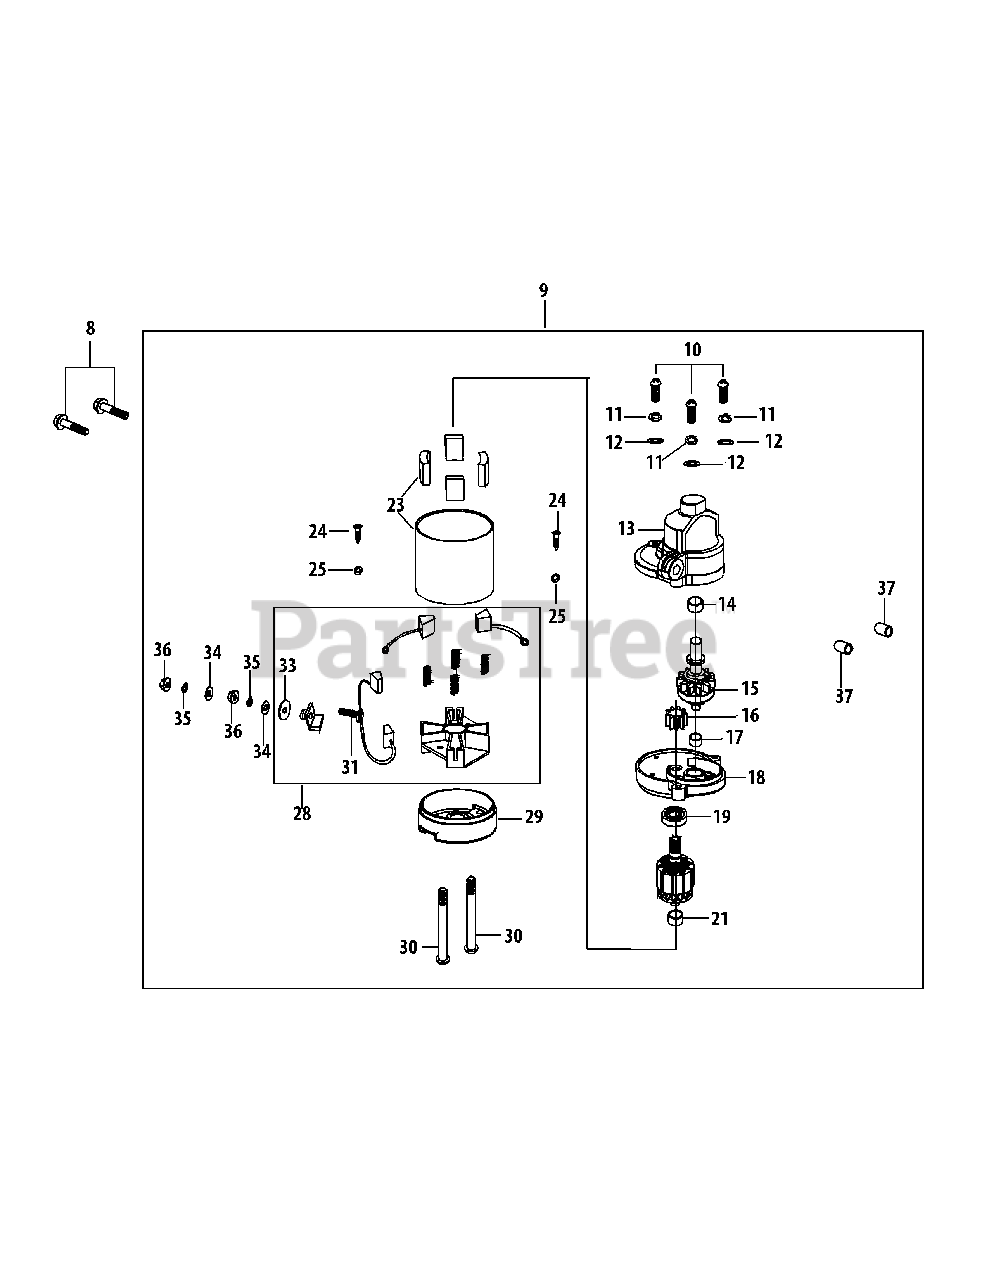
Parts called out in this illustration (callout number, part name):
8	Bolt M8×40
9	Starter Assembly
10	Screw M5×25
11	Lock Washer
12	Plain Washer
13	Electrical Starter Front Cover
15	Pinion/Clutch Assembly
18	Pinion Cover
19	Bearing 6001Zz
23	Starter Housing Assembly
25	Lock Washer
28	Brush Assembly
29	Electrical Starter Back Cover
30	Bolt M6×100
31	Bolt M6×30 Assembly
33	Insulation Washer
34	Plain Washer
35	Lock Washer
36	Nut M6
37	Dowel Pin 10×14
